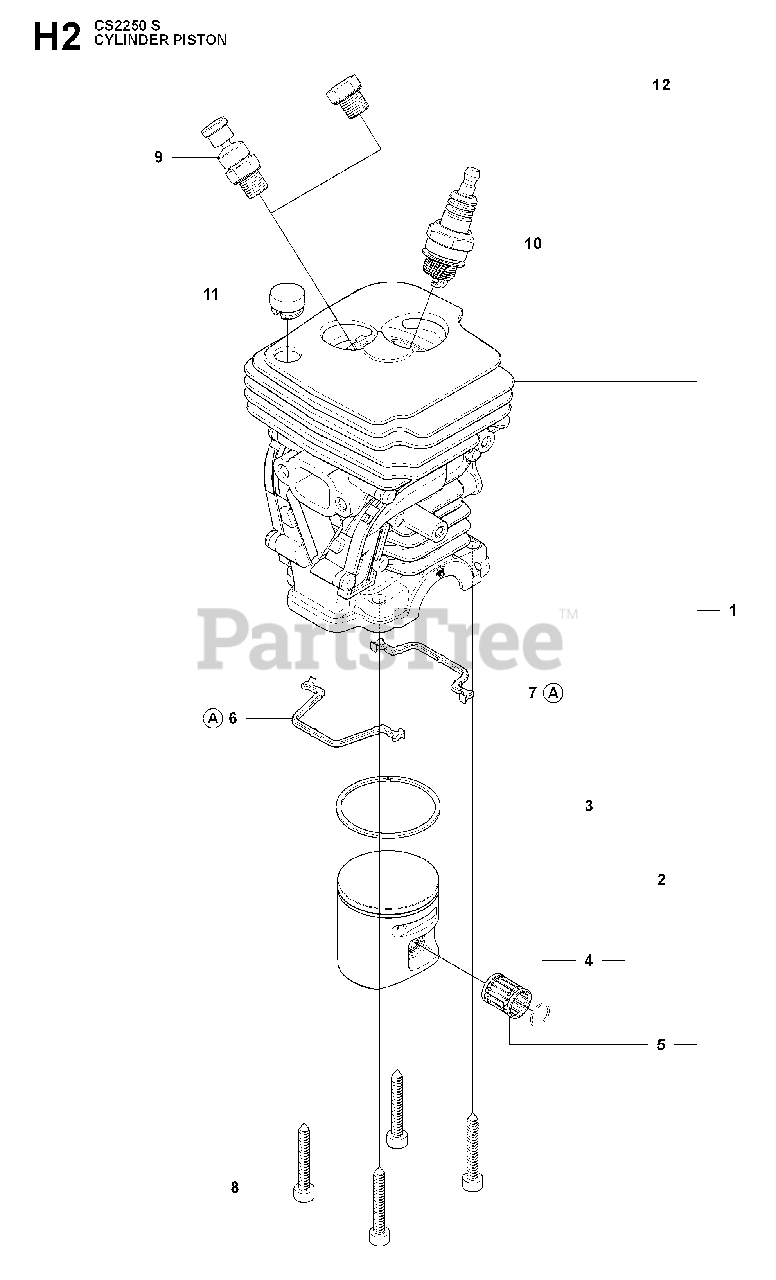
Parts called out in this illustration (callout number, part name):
2	PISTON ASSY
3	PISTON RING
5	RP SUPPORT BUSHING
9	DECOMPRESSION VALVE
10	BPMR7A NGK SPARK PLUG
12	CYLINDER PLUG
